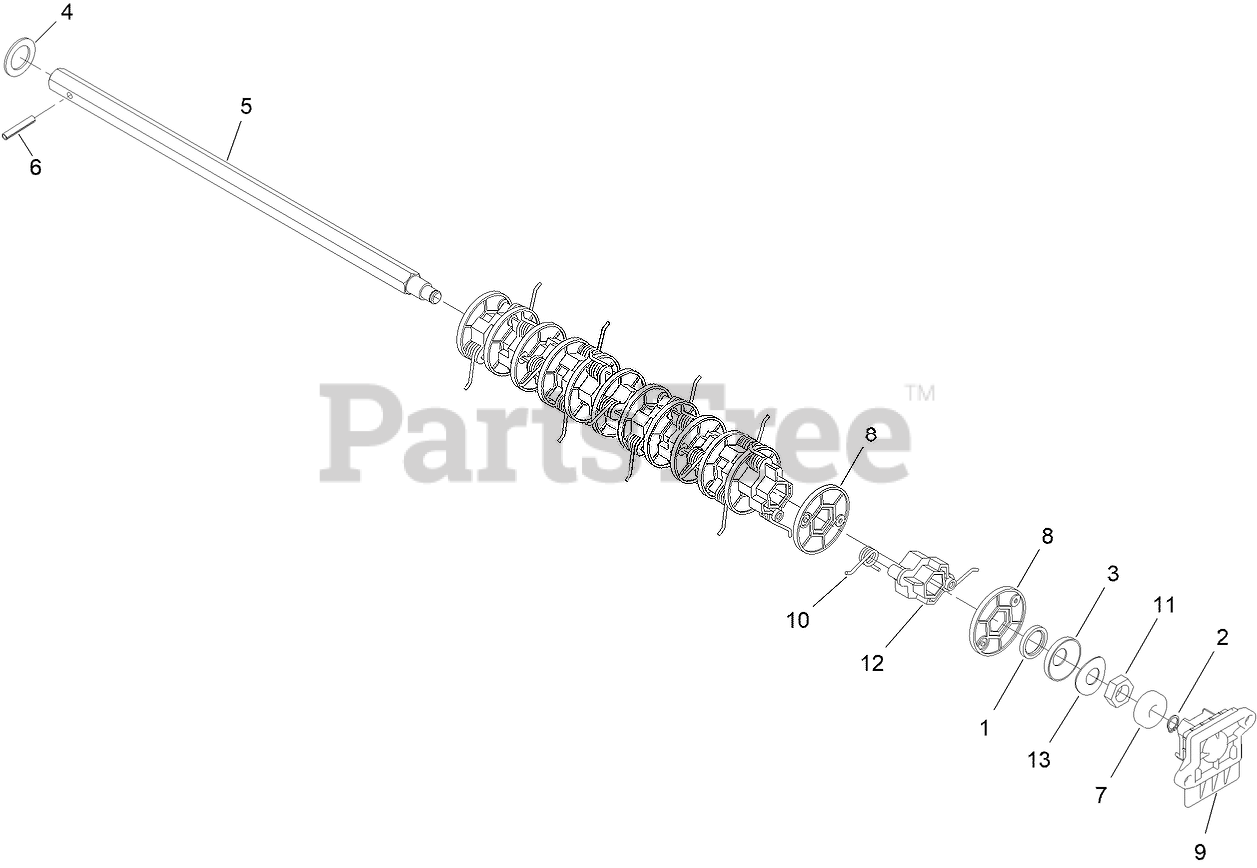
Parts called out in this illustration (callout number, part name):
1	SPACER
2	CIRCLIP
3	SHOULDER PIECE
4	WASHER
5	ROD-HEX
6	PIN-DOWEL
7	BEARING
8	DIVIDER-SPRING, PLASTIC AERATOR
9	BEARING HOUSING V2
10	SPRING TINE V2
11	NUT-HEX
12	SPRING RETAINER, AERATOR
13	WASHER-WAVE
